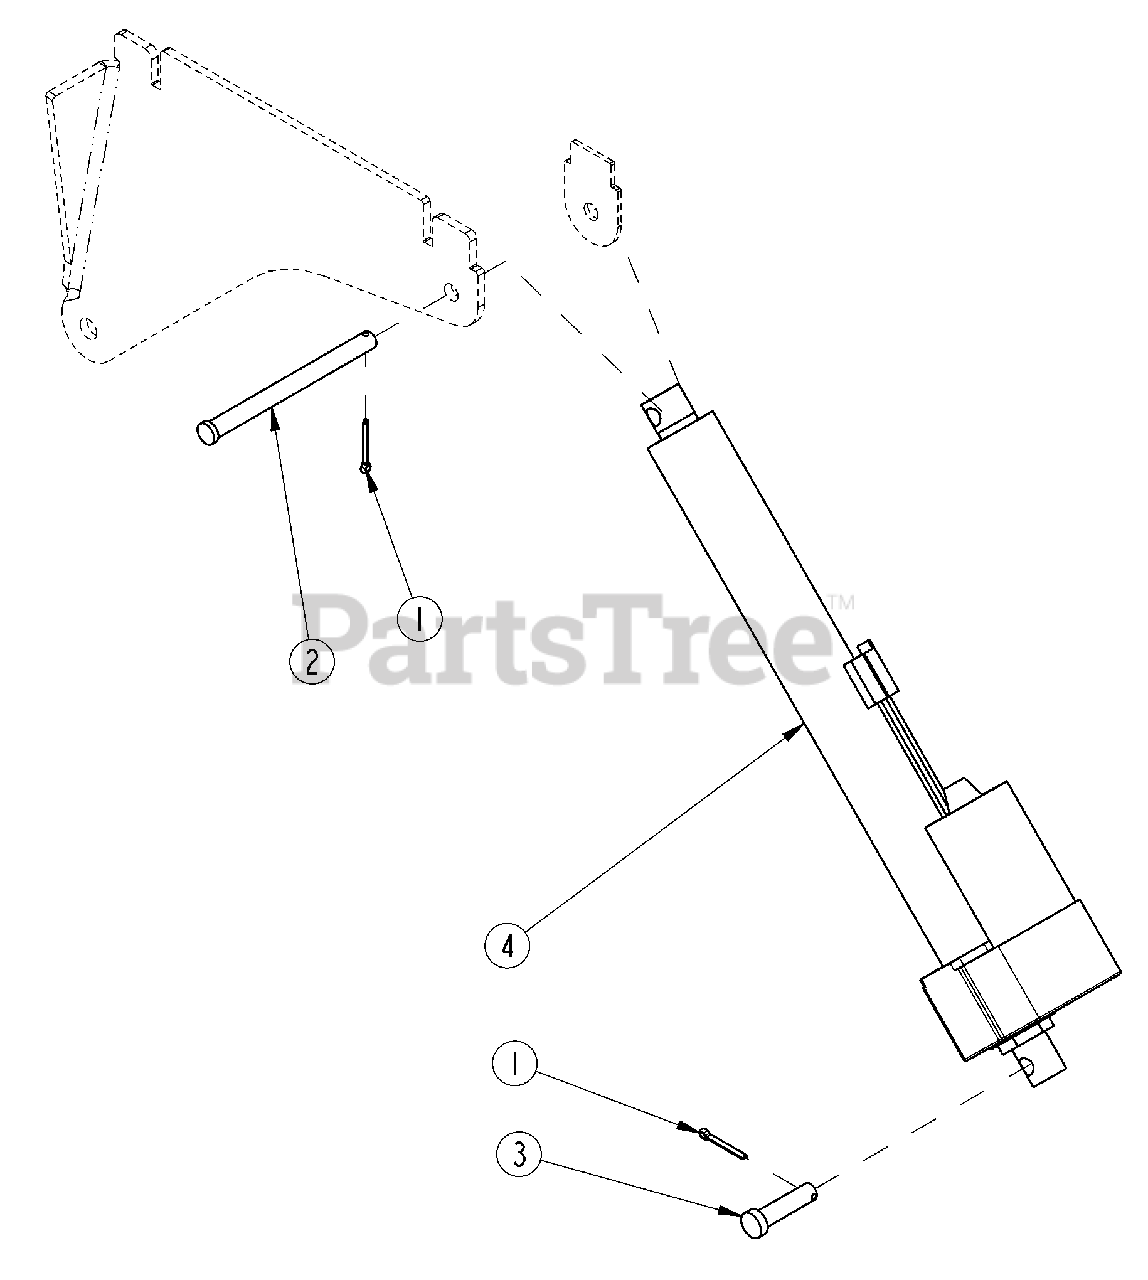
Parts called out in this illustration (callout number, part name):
1	RING, RUE .500 X .062 X 1.420
2	PIN, CLEVIS 1/2 X 5.76
3	PIN, CLEVIS .50 X 2.00 X 1.71 YWZC
4	ELECT. LINEAR ACTUATOR 12" STRK
